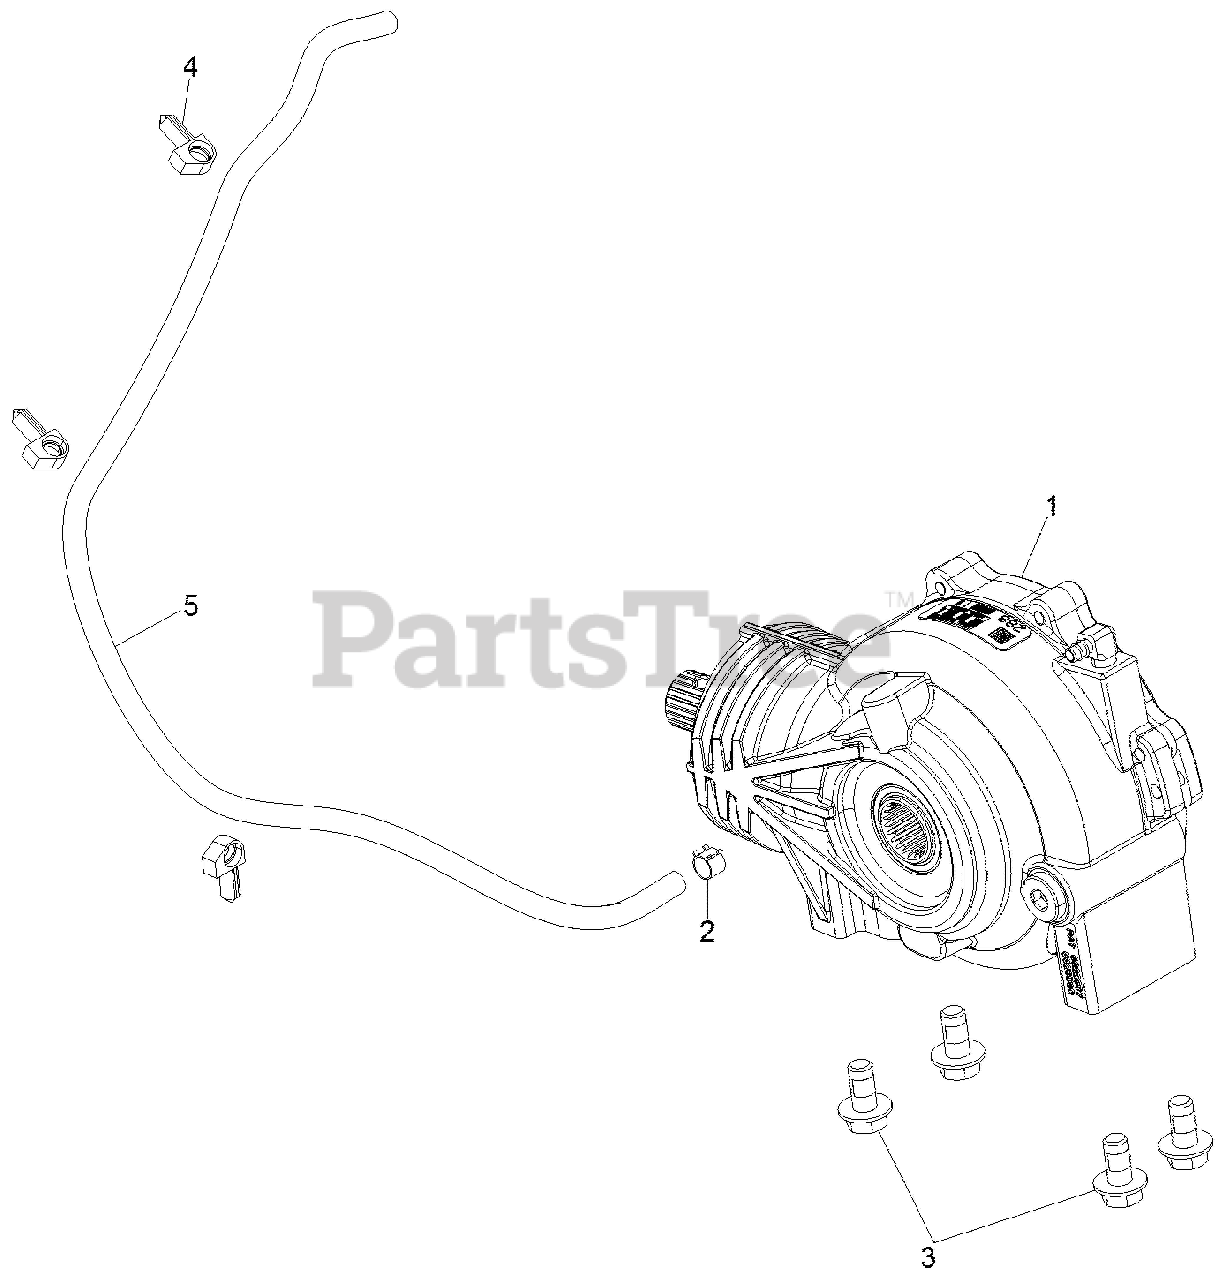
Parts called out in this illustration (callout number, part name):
1	ASM-GEARCASE,FRONT 12 POCKET
2	CLAMP,HOSE(10)
3	BOLT-M10X1.5X20,HXFLG,W/PATCH
5	LINE,FUEL,1/4 ID(1525 CM.)
